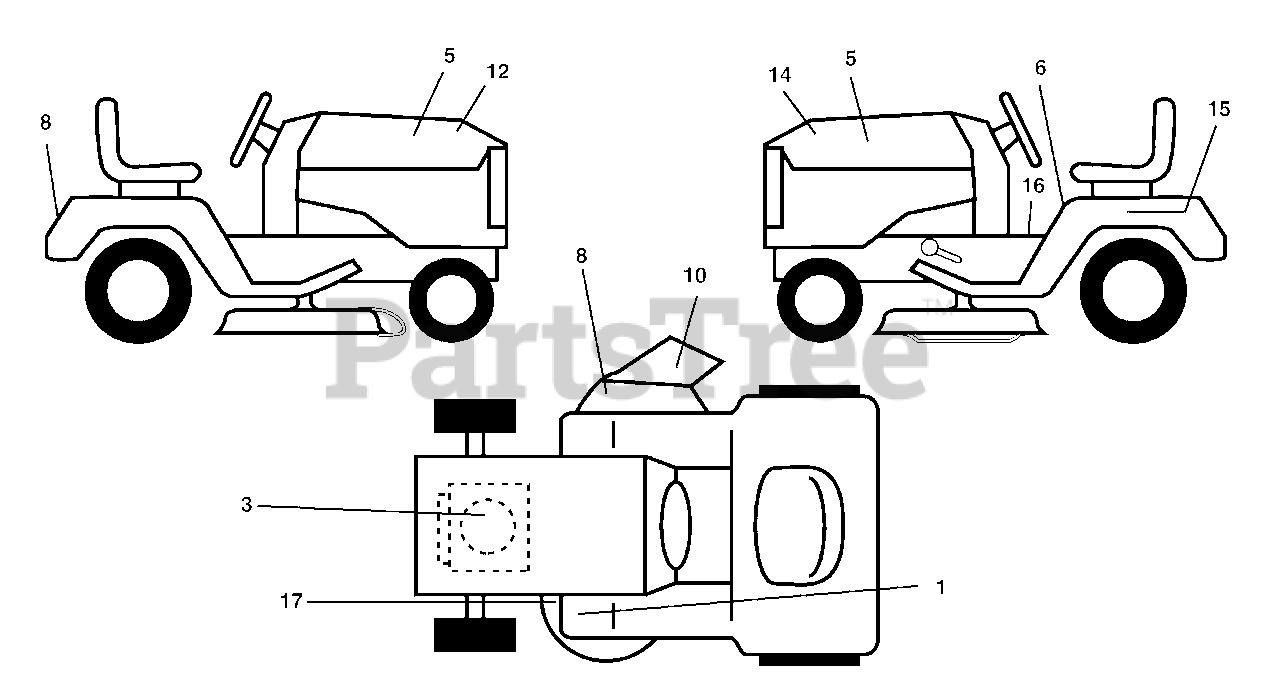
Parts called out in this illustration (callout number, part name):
1	Decal, Clutch/Brake English
3	Decal, Engine HP
5	Decal, Pnl Sd
6	Decal, Fender Danger English
8	Decal, Logo, Fender
10	Decal, Warning Multi-Language
12	Decal, Hood RH
14	Decal, Hood LH
15	Decal, Caution, Battery
16	Decal, Oper Sdl P/L Gear Dr Eng
17	Decal, V-Belt Sch.
